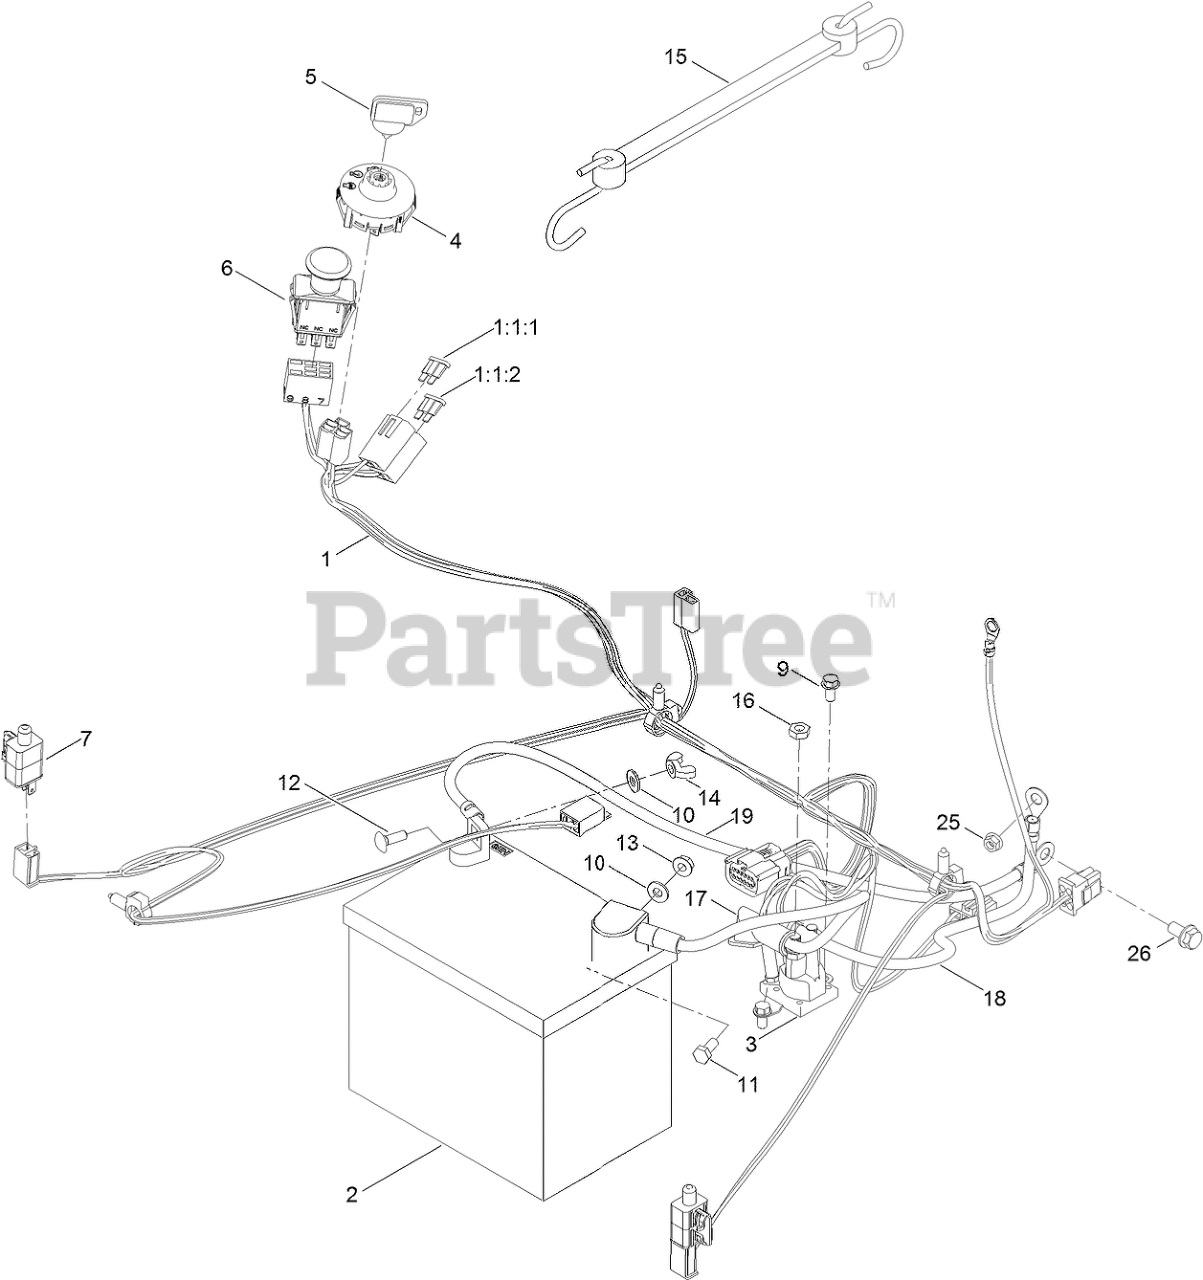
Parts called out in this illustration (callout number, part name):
1	HARNESS-WIRE
1:1:1	FUSE-BLADE, 30 AMP
1:1:2	FUSE-BLADE, 25 AMP
2	BATTERY
3	SOLENOID
4	SWITCH-IGNITION
5	KEY-IGNITION
6	SWITCH-PTO
7	SWITCH
9	SCREW-HWH
10	WASHER-FLAT
11	SCREW-HH
12	BOLT-CARR
13	NUT-HF
14	NUT-WING
15	HOLDDOWN-BATTERY
16	NUT-JAM
17	CABLE-BATTERY, RED
18	CABLE-BATTERY, POSITIVE
19	CABLE-BATTERY, BLACK
25	NUT-HF
26	SCREW-HHF
